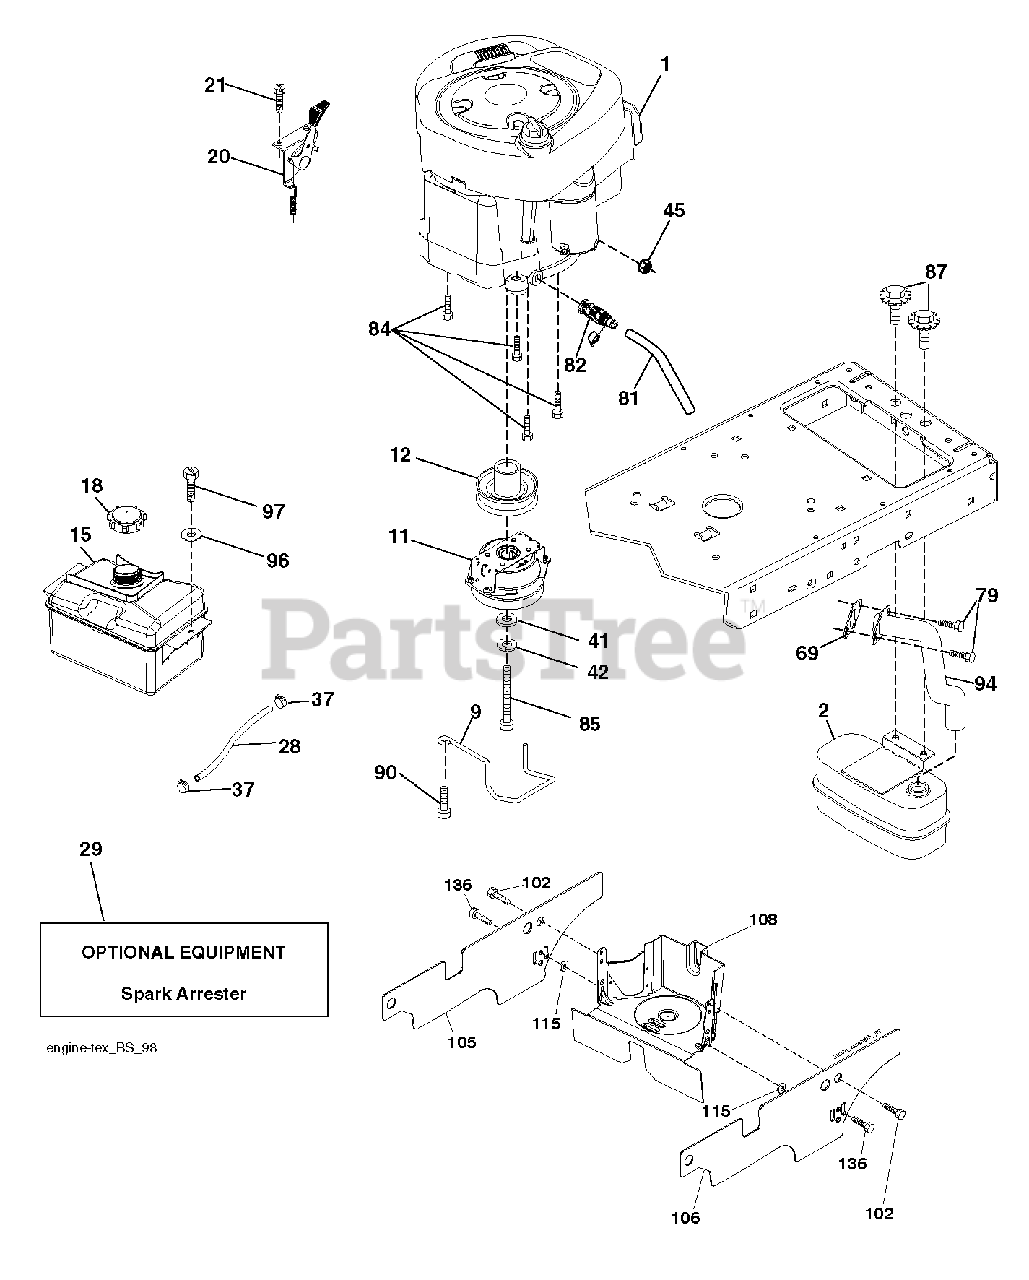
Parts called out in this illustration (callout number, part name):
2	MUFFLER.SINGLE.LRG.BRIGGS.KOHL
9	KEEPER BELT ENGINE
11	CLUTCH.OGURA.4.4PD.GT1.5-EH13V
12	PULLEY.ENGINE.TUFFTORQ
15	RP TANK FUEL FRT 1.5 GAL
18	CAP ASM.FUEL.2.25"FR.
20	THROTTLE.COBRA.21".RSTART.BLK
21	SCREW.#10 X 0.750.BOS
28	LINE.FUEL.20
29	KIT.SPARK ARRESTOR 794945 B&S
37	HOSE CLAMP
42	LOCKWASHER
45	NUT
69	REPL BY 532 27 22-93
79	SCREW.SOCKET HD.5/16-1
81	TUBE, DRAIN OIL ASM.
82	VALUE.OIL.DRAIN
84	SCREW.3/8-16
85	CLUTCH BOLT7/16-20X3.5 GR524HR
87	BOLT, 5/16-18 X 1 3/4
90	SCREW 3/8-16X1
94	EXHAUST.TUBE.B&S.28/31
97	SCREW HEXWSHR 1/4-20X3/4
102	SCREW
105	SHIELD.SIDE.LH.3842"TEX FRENCH
106	SHIELD.SIDE.RH.3842"TEX FRENCH
108	ENGINE COVER
115	PALNUT 1/4
136	SCREW.1/4-20X5/8
